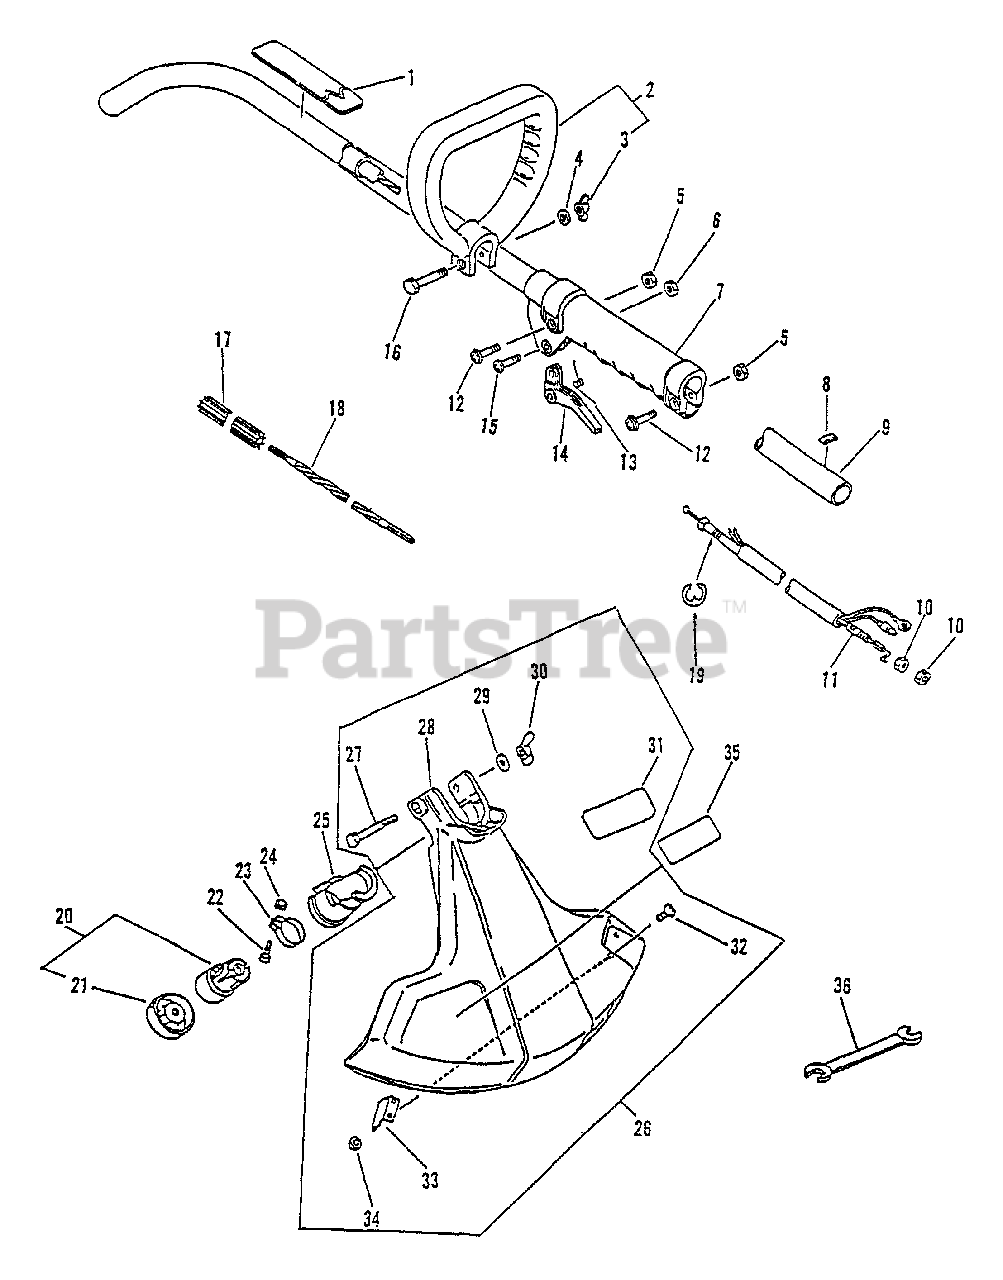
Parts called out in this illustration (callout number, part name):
1	LABEL - CAUTION
2	HANDLE ASSY
3	WINGNUT - 6
4	WASHER - 6
6	LOCKNUT - 5
7	GRIP, HANDLE
8	LABEL - ALIGNMENT
9	MAIN PIPE ASSY
11	CABLE, THROTTLE
12	SCREW - 5X25
13	SPRING, TRIGGER
14	TRIGGER, THROTTLE
15	SCREW - 5X30
16	BOLT - 6X40
17	LINER - FLEXIBLE
18	DRIVESHAFT - FLEXIBLE
19	RING, RETAINING - 5
20	GEAR CASE ASSY
21	ADAPTOR, BLADE - UPPER
22	SCREW - 5X10
25	BRACKET, BEARING CASE
26	DEBRIS SHIELD KIT
27	BOLT - 6X50
28	SHIELD, DEBRIS - PLASTIC
29	WASHER - 6
30	WINGNUT - 6
31	LABEL - CAUTION
32	SCREW - 5X16
33	KNIFE, TRIMMER LINE
35	LABEL - ECHO
36	SPANNER - 8X10mm
